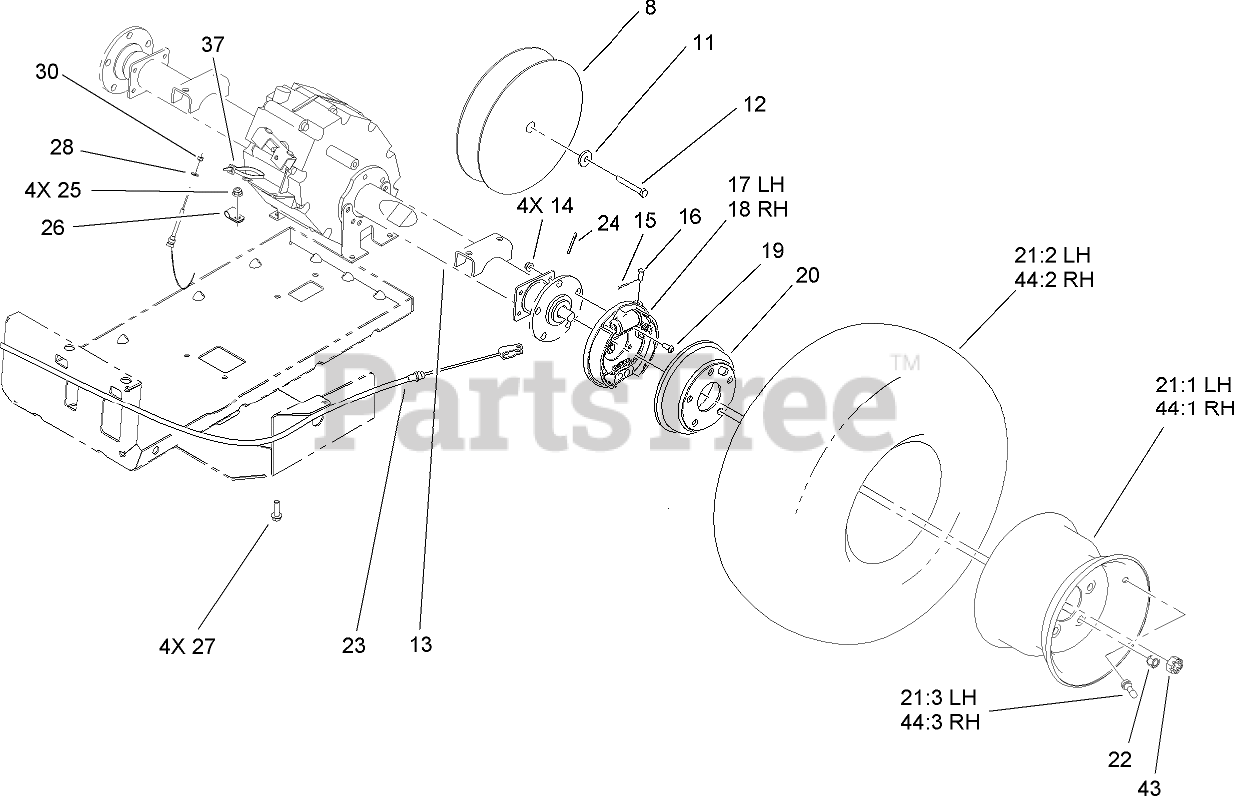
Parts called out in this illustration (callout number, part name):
8	CLUTCH-DRIVEN
11	WASHER-STEPPED
12	Screw-HH
13	Transaxle
14	NUT-HF, NI
15	PIN-COTTER
16	PIN-CLEVIS
17	LH BRAKE ASM
18	RH BRAKE ASM
19	SCREW-HSBH
20	DRUM-BRAKE
21	TIRE AND WHEEL ASM
21:1	WHEEL-5 BOLT
21:3	STEM-VALVE
22	NUT-LUG
23	CABLE-BRAKE, PARK
24	PIN-COTTER
25	NUT-HF, NI
26	R-CLAMP
27	SCREW-HHF
28	WASHER-PLAIN
30	NUT-LOCK, NI
37	TIE-CABLE
43	NUT-CASTLE
44	TIRE AND WHEEL ASM
44:1	WHEEL-5 BOLT
44:3	STEM-VALVE
